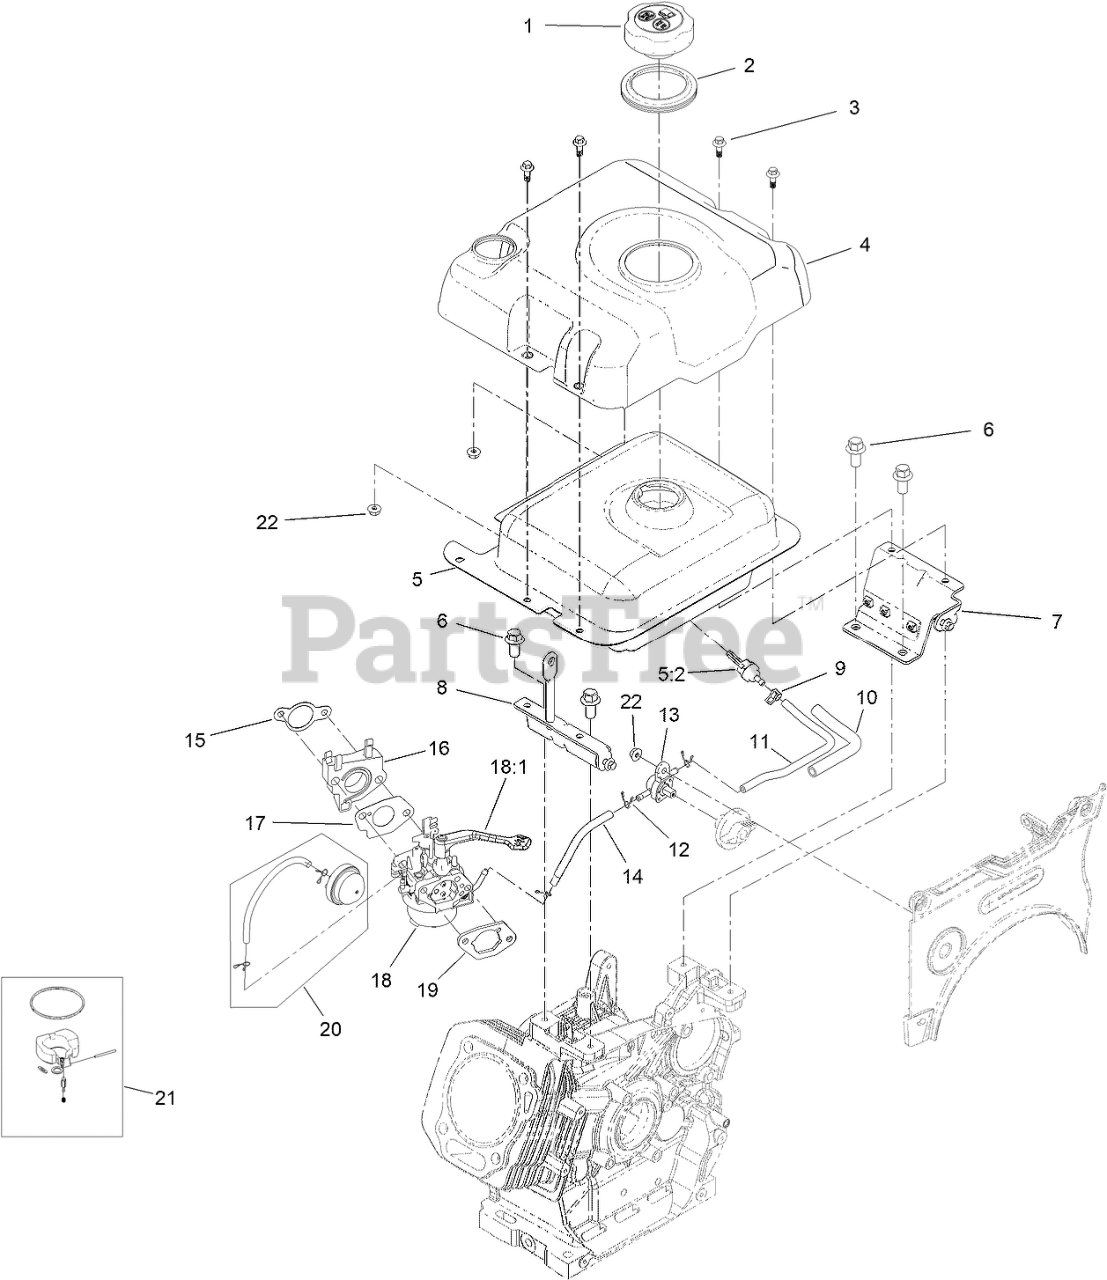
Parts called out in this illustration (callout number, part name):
1	CAP-FUEL
2	INSERT-COVER, TANK
3	SCREW-HHF
4	COVER-TANK, FUEL
5	FUEL TANK AND FILTER ASM
5:2	FILTER-FUEL
6	SCREW-HHF
7	BRACKET-TANK, RIGHT
8	BRACKET-TANK, LEFT
9	CLAMP-HOSE
10	SLEEVE-ABRASION
11	HOSE-FUEL
12	CLAMP-HOSE
13	VALVE-FUEL
14	HOSE-FUEL
15	GASKET-CARBURETOR
16	INSULATOR-CARBURETOR
17	GASKET-CARBURETOR
18	CARBURETOR ASM
18:1	LEVER-CHOKE
19	GASKET-COATED, RUBBER
20	PRIMER KIT
21	INTERNAL CARB SERVICE KIT
22	NUT-FLANGE
